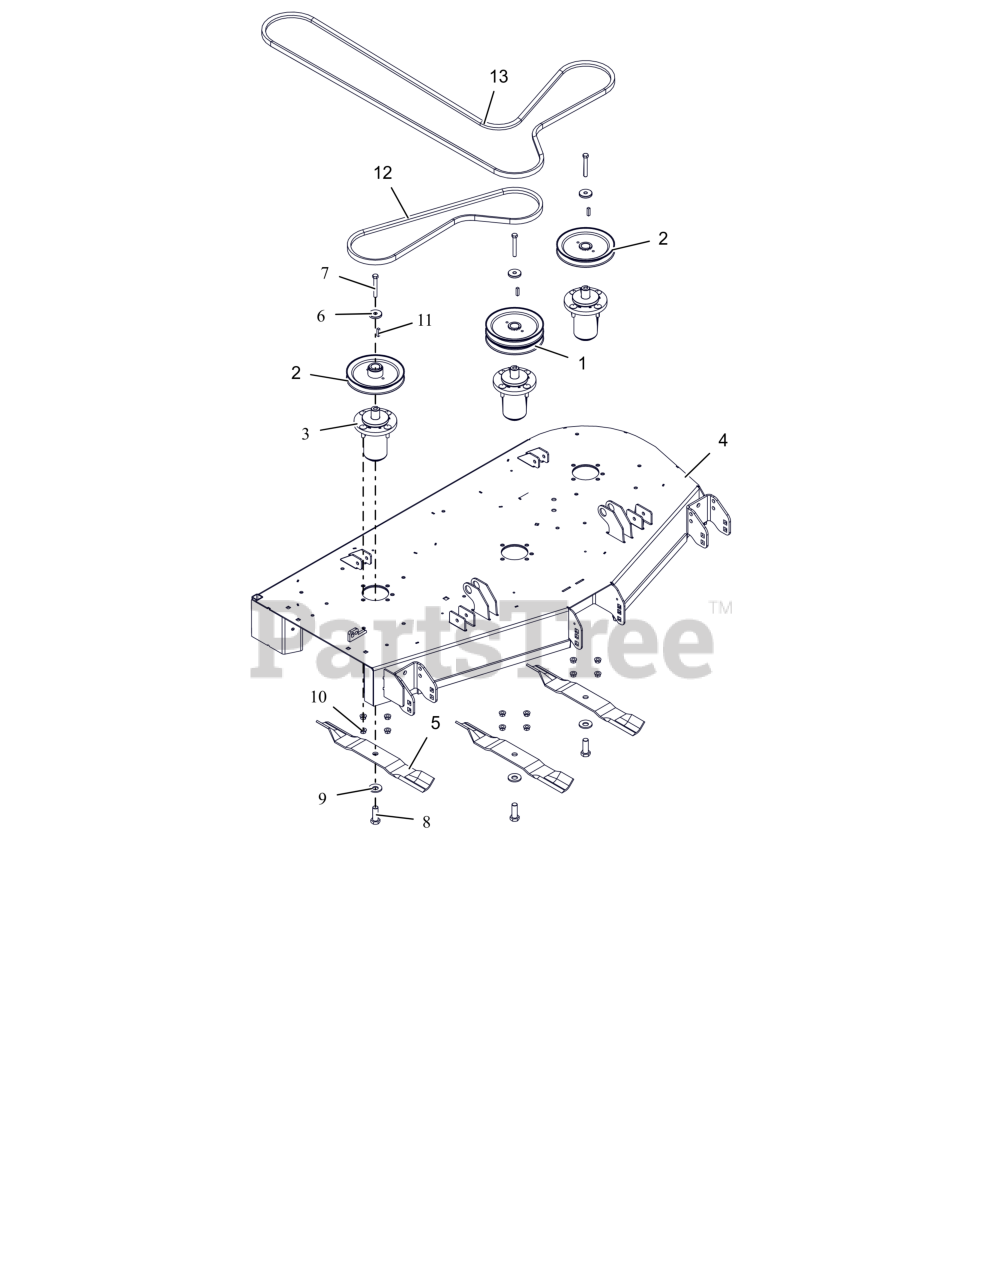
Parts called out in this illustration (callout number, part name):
1	PULLEY, DOUBLE 1.000 ID X 6.750 OD-BLACK
2	PULLEY, V-1.000 ID X 6.750 OD
3	ASM, MAINT FREE ALUM SPINDLE
4	KIT-DECK-52" W/DECALS-ARIENSCE
5	BLADE, 18"
6	RETAINER, SHEAVE
7	BLT, HEX .38-16X2.75 G8 ZCC
8	BLT, HEX .62-18X1.75 G8 ZCC
9	WSHR-BLVL .669X1.535X.138
10	NUT-LK-CTR-FLG .375-16 GF ZCC
11	KEY, SQ .25X.25X1.00 RC 40-50
12	V-BELT, B-COGGED
13	V-BELT, HB SECTION
